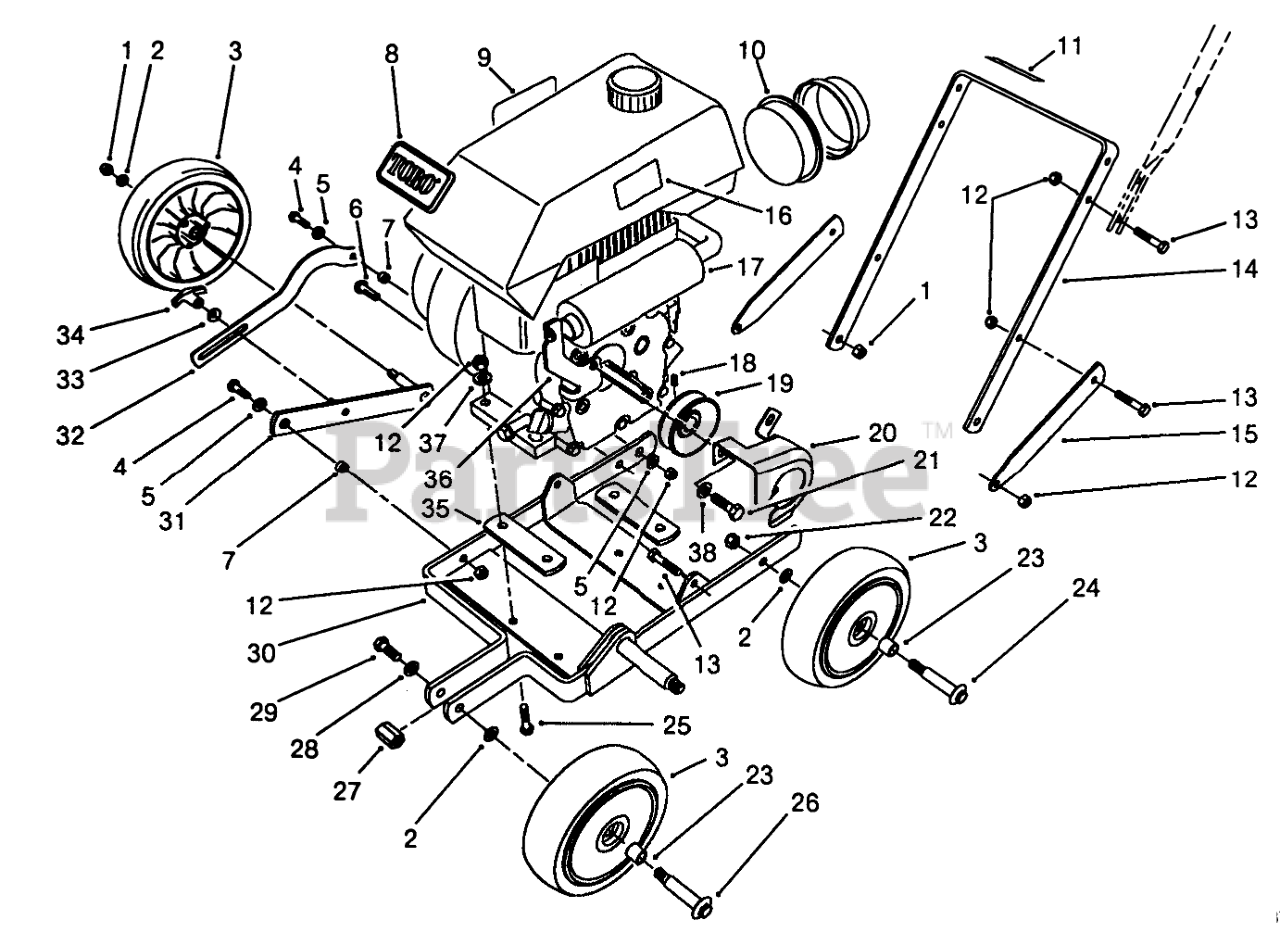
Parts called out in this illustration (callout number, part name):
1	NUT-LOCK
2	WASHER
3	Wheel & Tire Assembly (Incl. Ref. #23)
4	SCREW-HH
5	WASHER-FLAT
6	3/8-24 X 1.00HEX BU. HD
7	WHEEL MT BUSHING
8	TORO LOGO PLT
9	OPERATING INST DECAL
10	FILTER FOAM
11	Decal-Warning
12	NUT-LOCK, NI
13	SCREW-HH
14	LOWER HANDLE
15	SUPPORT HANDLE
16	Decal-Hot
17	Engine (Complete)
18	SCREW-SET
19	2HP PULLEY
20	ENG. PULLEY GUARD
21	SCREW-HH
22	NUT-HEX
23	BUSHING
24	WHEEL BOLT
25	SCREW-HH
26	BOLT-WHEEL
27	HEX SPACER
28	WASHER-LOCK
29	SCREW-HH
30	Frame-Edger
31	WHEEL MOUNT WA
32	AXLE LINK
33	BELLEVILLE SPRING WASHE
35	Pats-Spacer
36	SPRING BRKT R
37	WASHER-PLAIN
38	WASHER-LOCK
